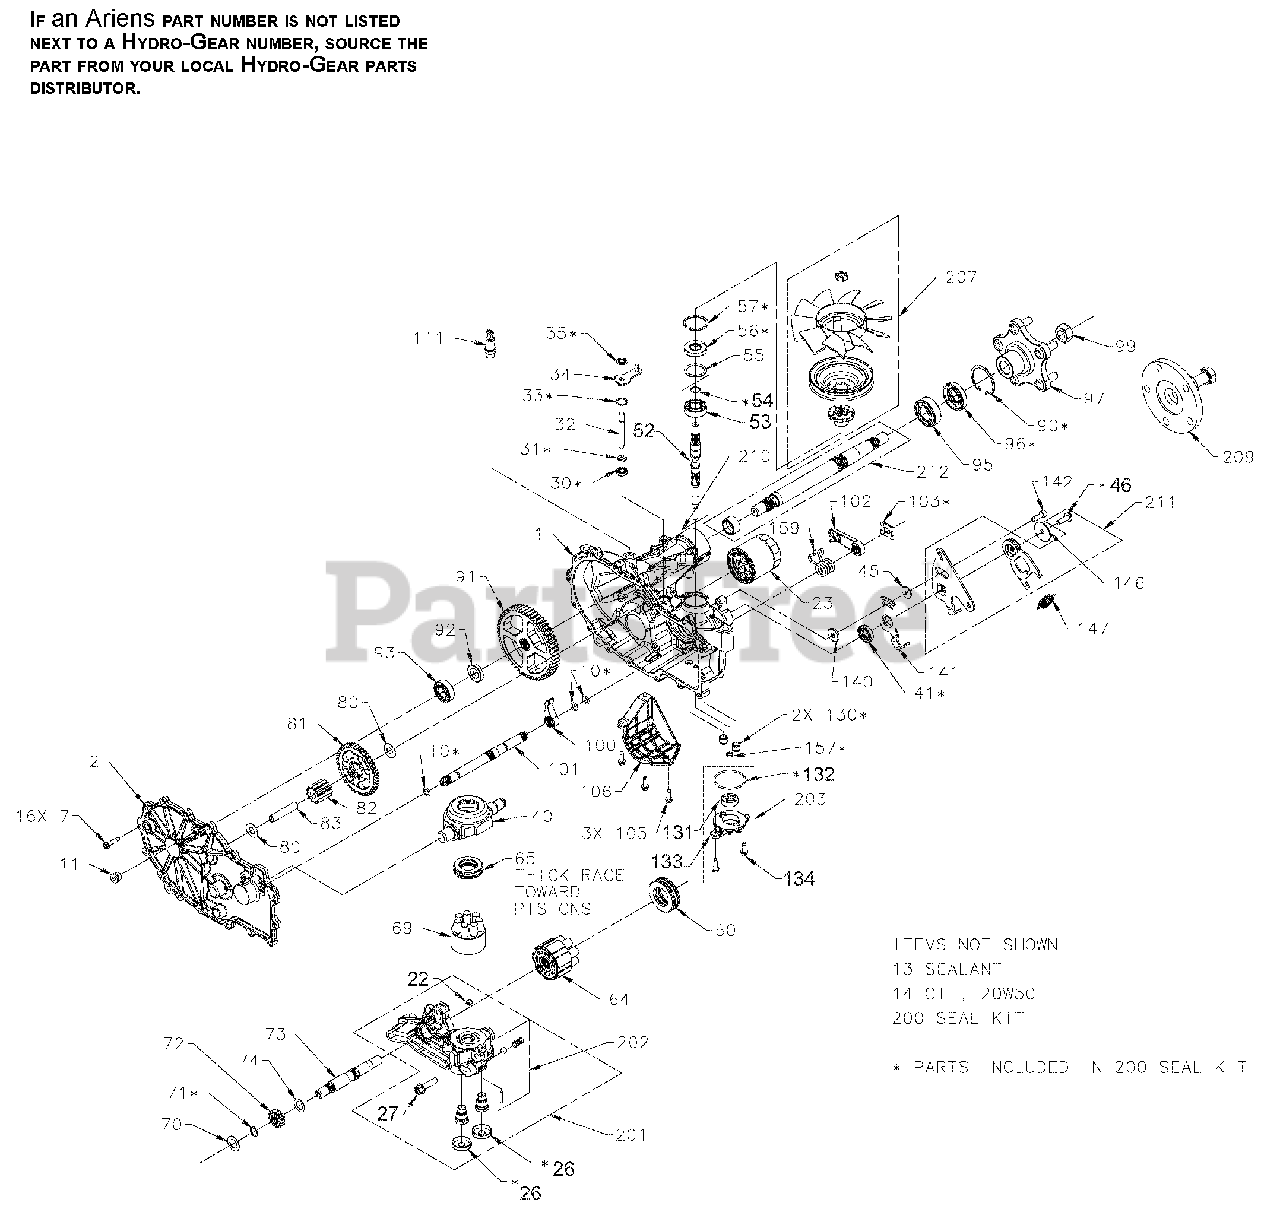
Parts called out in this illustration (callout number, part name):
1	Kit, Main Housing Left Hand
2	Kit, Side Housing Left Hand
7	HFHCS 1/4-20 X 1.25"
11	PLUG, STEEL (WITH SEAL)
22	PLATE, BYPASS
23	Filter, Oil
30	SEAL, LIP .375X.75X.25
31	RING. RETAINING
32	Rod, Bypass
33	RING, RET .750
34	Arm, Bypass
35	RING, RTNG .
40	TRUNNION, SWASHPLATE
45	WASHER
46	TWHCS 5/16-24 X 1.00
52	Shaft, Input
53	BRG, BALL 17X40X12
54	Ring, Ret Wire .561 ID
55	WASHER 1.23X1.56X.04
57	RING, RET 1.56 INT
60	Bearing, Thrust
65	BEARING. THRUST 30 X 52 X 13
69	Assembly, Block, 7 Piston
70	WASHER .63X1.0X.05
71	RING, RET 62 EXT
72	Gear, 13T, Steel
73	Shaft, Motor
74	WASHER .71 X 1.16 X .04
80	WASHER .5X1.0X.032
82	Gear, 11T, Steel
83	JACK SHAFT (PIN)
90	RING, RETAINING
95	BEARING, BALL 25.4 X 52 X 15
96	SEAL, LIP
97	Kit, Hub, 4 Bolt
99	NUT, HEX, LOCK 3/4-16
100	Pawl, Brake
101	Brake Shaft
102	Brake Handle
103	Clip, Retaining
105	HFHCS 1/4-20X.75
106	Guard, Filter, RH
111	Fitting, Str 9/16-18 SAE .5 Barb
130	Tube, Connecting
131	GEROTOR
133	Cover, Charge Pump
134	HFHCS 1/4-20X.75
141	Arm, Neutral Left
142	SHCS 5/16-24X1 PATCH
146	WASHER
147	Spring, Extension Rtn - 34 lbs
156	Cap, Axle
157	Seal, LIP 8 x 12 x 3 VC
159	Spring, Torsion CCW
200	Kit, Seal ( * - parts included in this kit)
201	Kit, Center Section, RH, CHRG
202	Kit, Charge Relief
207	Kit, Fan and Pulley
209	Hub Puller, 4 Bolt
NS	SEALANT TUBE 10.1OZ.
NS	20W50 Oil
